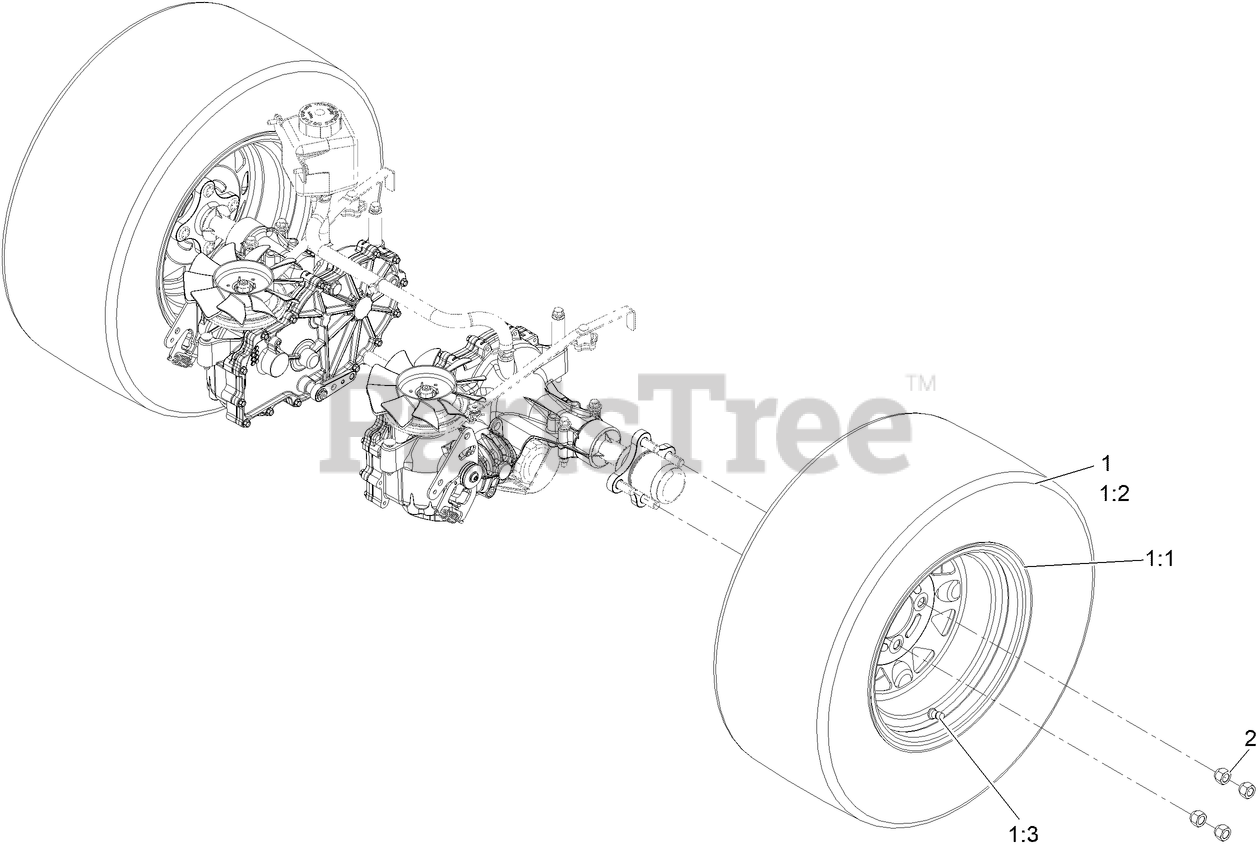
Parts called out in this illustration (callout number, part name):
1	WHEEL AND TIRE ASM
1:3	VALVE
2	NUT-LUG
